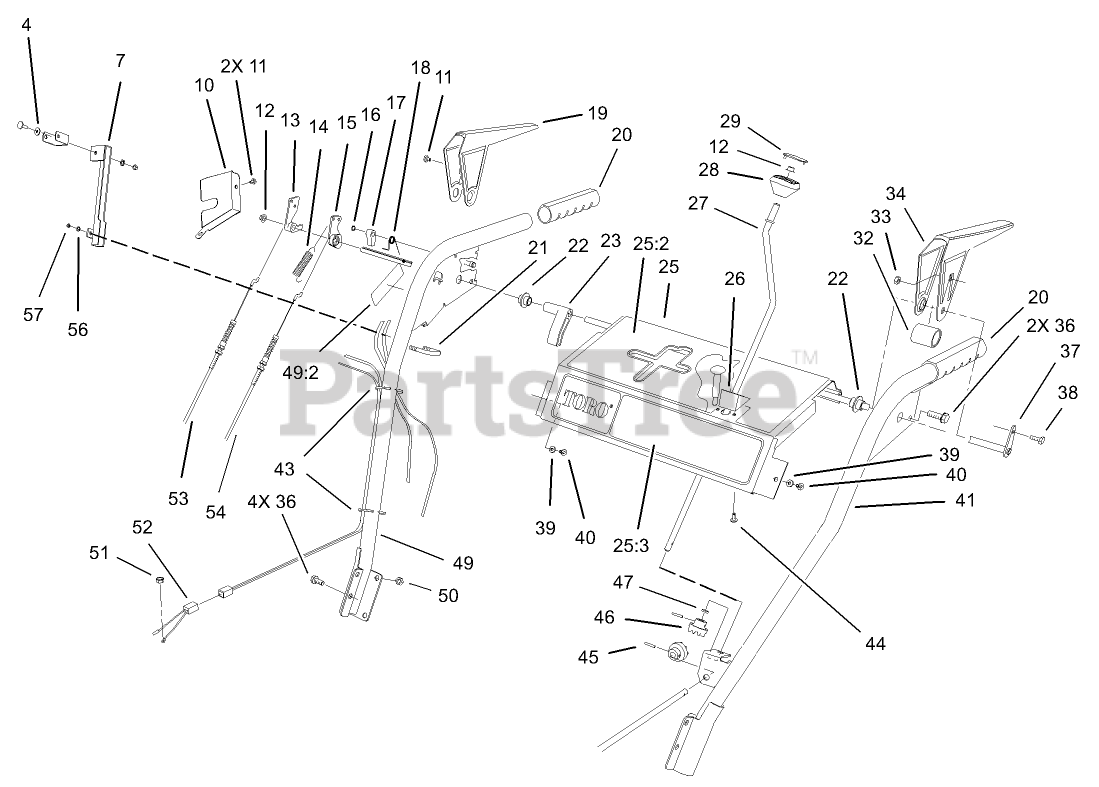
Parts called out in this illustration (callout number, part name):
4	WASHER-FLAT
7	MOUNT ASM-LIGHT
10	COVER-LOCK, LEVER
12	NUT-PUSH
14	SPRING-EXTENSION
15	CAM-RELEASE
16	RING-RETAINING
17	LATCH-LOCKING
18	SPRING-TORSION
19	LEVER-TRACTION, RH
20	GRIP-HANDLE
21	U-BOLT
22	BUSHING-LEVER
23	LEVER-TRIP
25	CONTROL PANEL ASM
25:2	DECAL-CONTROL
25:3	DECAL - FRONT PANEL
26	PLATE-GUIDE
27	CRANK-ROD, CHUTE
28	KNOB-CONTROL, CHUTE
29	COVER-KNOB
32	SPACER-LEVER, TRACTION
33	NUT-LOCK, NI
34	LEVER-TRACTION, LH
36	SCREW-HWHTF
37	CROSS ROD ASM
38	SCREW-HWH
39	WASHER-FLAT
40	SCREW-HWHTF
41	LH HANDLE ASM, 24"-32"
43	TIE-CABLE
44	SCREW
45	PIN-SPRING
46	GEAR-UNIVERSAL
47	WASHER-RUBBER
49:2	DECAL-ADJUSTMENT
50	NUT-LOCK, NI
51	NUT-HEX
52	WIRE ASM
53	CABLE-IMPELLER
54	CABLE-TRACTION
56	WASHER-PLAIN
57	NUT-LOCK, NI
